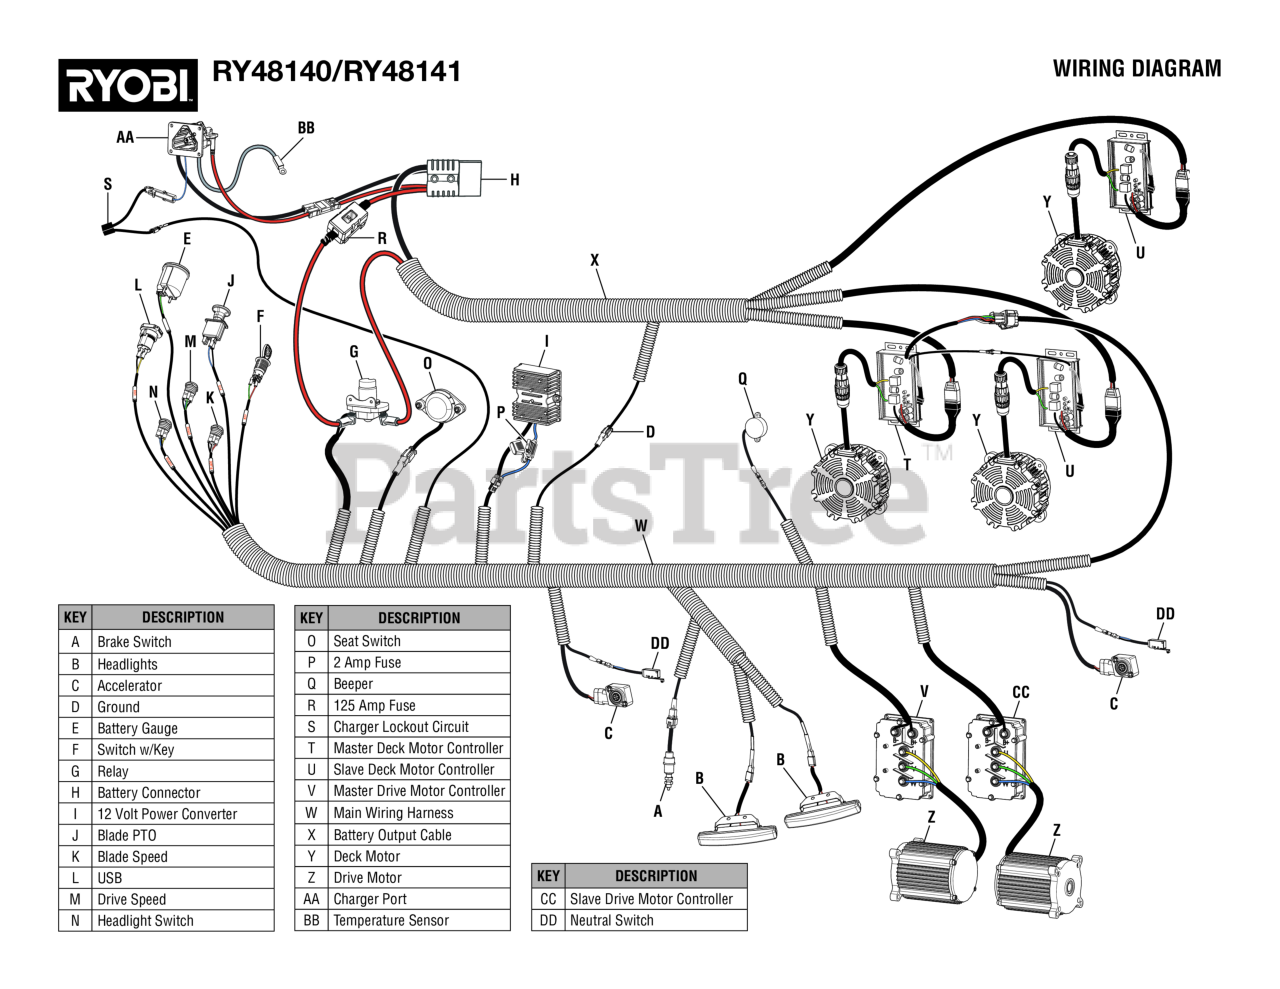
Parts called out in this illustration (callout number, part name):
A	Brake Switch
B	Headlights
C	Accelerator
D	Ground
E	Battery Gauge
F	Switch w/Key
G	Relay
H	Battery Connector
I	12 Volt Power Converter
J	Blade PTO
K	Blade Speed
L	USB
M	Drive Speed
N	Headlight Switch
O	Seat Switch
P	2 Amp Fuse
Q	Beeper
R	125 Amp Fuse
S	Charger Lockout Circuit
T	Master Deck Motor Controller
U	Slave Deck Motor Controller
V	Master Drive Motor Controller
W	Main Wiring Harness
X	Battery Output Cable
Y	Deck Motor
Z	Drive Motor
AA	Charger Port
BB	Temperature Sensor
CC	Slave Drive Motor Controller
DD	Neutral Switch
